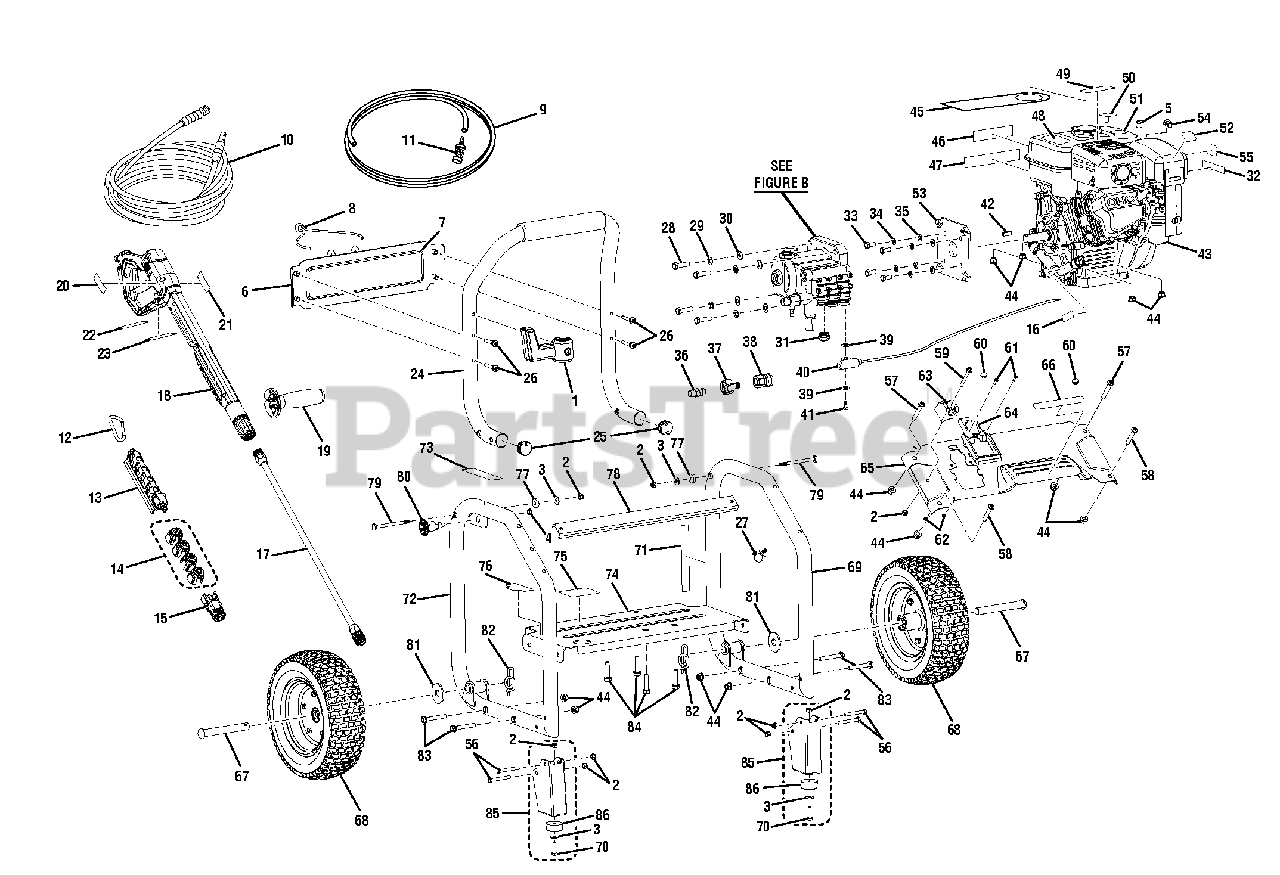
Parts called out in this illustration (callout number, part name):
1	Wand Holder Assembly
2	Lock Nut (1/4-20)
3	Washer (1/4 in)
4	Lock Nut (1/2-20)
5	Swivel Bushing
6	Logo Plate
7	Performance Label
8	Bungee Cord and Bead Assembly
9	Injection Hose
10	High Pressure Hose (30 ft)
11	Injection Hose Filter
12	Spring Clip
13	Storage Holder
14	Nozzle Kit w/Shroud
15	Soap Blaster Nozzle
16	Oil Dipstick Label
17	Spray Wand
18	Trigger Handle Assembly
19	Auxiliary Handle Assembly
20	Trigger Guard Warning Label (English)
21	Trigger Handle Label
22	Trigger Handle Max Pressure Label
23	Trigger Guard Warning Label (French/Spanish)
24	Handle Assembly
25	Handle Tube Cap
26	Bolt (1/4 x 42 mm, Pan Hd)
27	Idle Down Cable Clamp
28	Bolt (3/8-16 x 1-3/8 in, Hex Hd)
29	Lock Washer (3/8 in)
30	Washer (3/8 in)
31	Idle Down Plug
32	EMC Label
33	Bolt (5/16-24 x 3/4 in, Hex Hd)
34	Lock Washer (5/16 in)
35	Washer (5/16 in)
36	Thermal Release Valve
37	Garden Hose Coupler w/Filter
38	Quick Disconnect (Female)
39	Seal
40	Idle Down Assembly
41	Idle Down Bolt (Special)
42	Output Shaft Key (27 mm)
43	SP210 Hori Engine
44	Lock Nut (M8 x 125 mm)
45	Hang Tag (Engine)
46	Add Lubricant Label
47	Combustion Warning Label
48	Danger Label (English)
49	Danger Label (French)
50	E-85 Label
51	Check Oil Label
52	Hot Muffler Label
53	Pump Flange
54	Cable Clamp
55	Pressure Release Label
56	Bolt (1/4-20 x 52 mm, Hex Hd)
57	Bolt (M8 x 70 mm, Hex Soc Hd)
58	Bolt (M8 x 46 mm, Hex Soc Hd)
59	Screw (1/4-20 x 21 in, T30, Torx Hd)
60	Bumper Handle
61	Screw (M4 x 12 mm, Hex Button Hd)
62	Lock Nut (M4)
63	Wand Holder
64	Trigger Handle Storage
65	Face Plate
66	Hot Surface Label
68	Wheel (D12 in x 3 in)
69	Left Frame
70	Bolt (1/4-20 x 1 in)
71	Quick Start Label (Engine)
72	Right Frame Assembly
73	Handle Release Label
74	Engine Plate
75	Data Label
76	Quick Start Label (Pump)
77	Washer (OD20 x ID8 x 45t)
79	Connector Pin (1/4 in)
80	Handle Knob
81	Washer (5/8 in)
82	Hitch Pin
83	Bolt (M8 x 55 mm, Hex Hd)
84	Bolt (M8 x 45 mm, Hex Hd)
85	Foot Assembly
